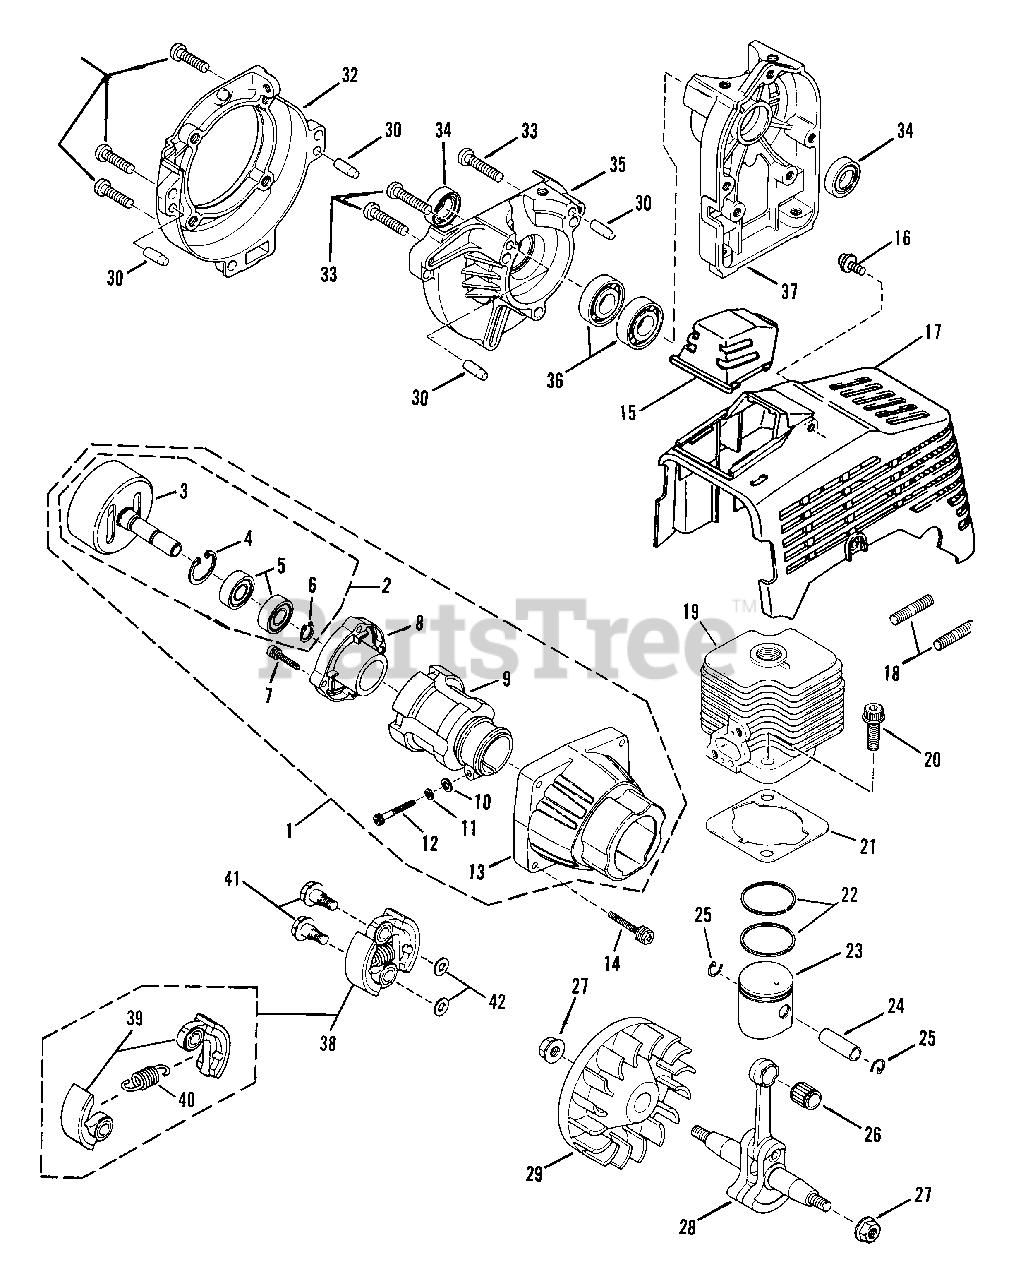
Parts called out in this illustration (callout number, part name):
1	ASSEMBLY, Clutch Case
2	ASSEMBLY, Clutch Drum
3	DRUM, Clutch
4	RING, Snap 26mm
5	BEARING
6	RING, Snap 10mm
7	SCREW, M5 x 20mm
8	COVER, Clutch Bearing
9	RING, Insert
10	WASHER, Flat MS
11	WASHER, Lock M5
12	SCREW, M5 x 25mm Socket
13	CASE, Clutch
14	BOLT, M6 x 28mm Hex Head
15	GUARD, Spark Plug
16	SCREW, M5 x 12mm
17	COVER, Cylinder
18	BOLT, Stud
19	CYLINDER
20	BOLT, Flange
21	GASKET, Cylinder
22	RING, Piston
23	PISTON
24	PIN, Piston
25	CLIP, Piston Pin
26	BEARING, Needle
27	NUT, Conical
28	CRANKSHAFT ASSEMBLY
29	FLYWHEEL
30	PIN, Dowel
31	BOLT/Washer
32	CASE, Fan
33	SCREW, M5 x 25mm
34	SEAL, Oil
35	CASE, Drive
36	BEARING, Ball
37	CASE, Starter
38	CLUTCH ASSM'Y.
39	SHOE, Clutch
41	BOLT, Clutch
